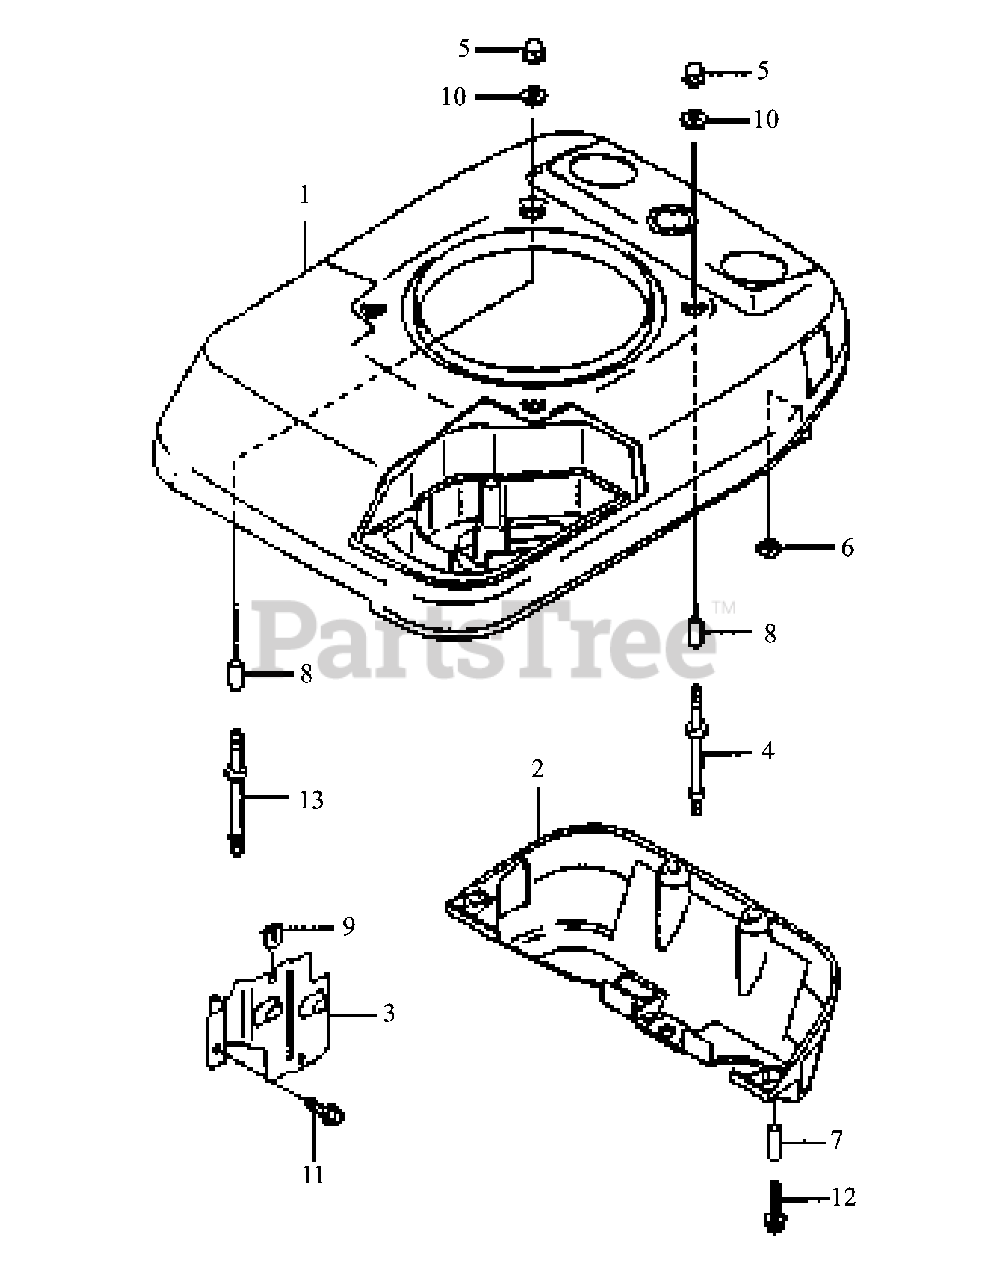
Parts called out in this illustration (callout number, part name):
6	Nut 6mm
7	Spacer 6.2x7.8x17
8	Spacer 6.2x7.8x22
10	Washer 65x18x2.0
11	Bolt, Flange
12	Bolt, Flange
